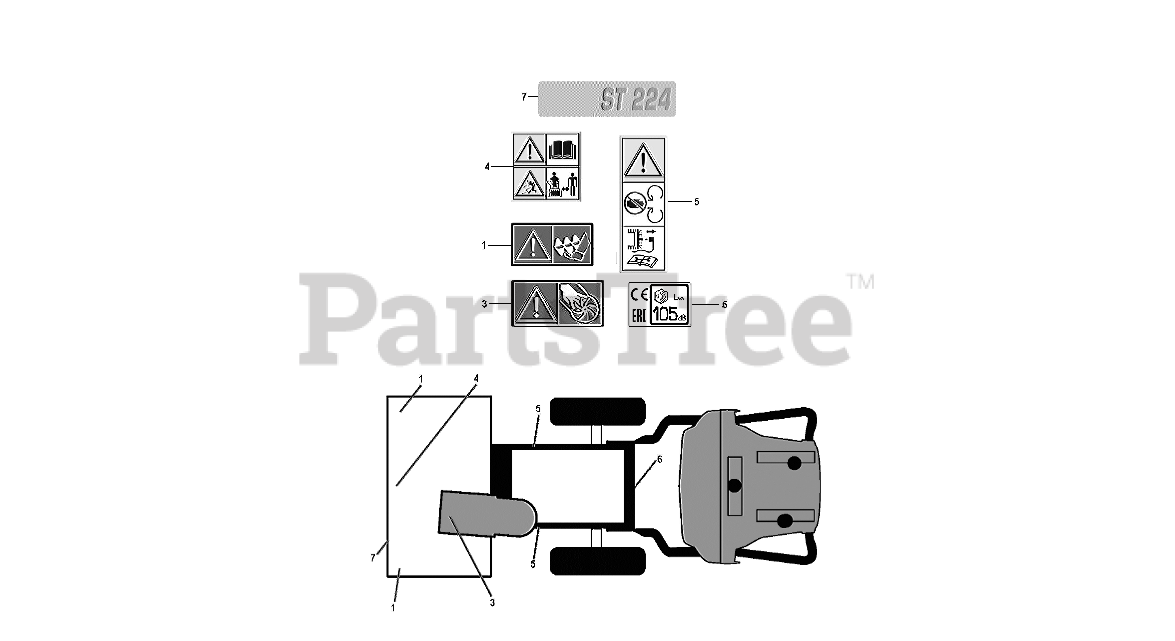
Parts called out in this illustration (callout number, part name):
1	DECAL.AUGER.SAFETY.
3	DECAL.CHUTE.SAFETY.EU/SC.17
4	DECAL.AUGER."
5	DECAL.BELT.GUARD.
6	DECAL.NOISE.LEV.105/CE.EAC.UKR
7	DECAL.AUGER HSG.HUSQ.ST 224
